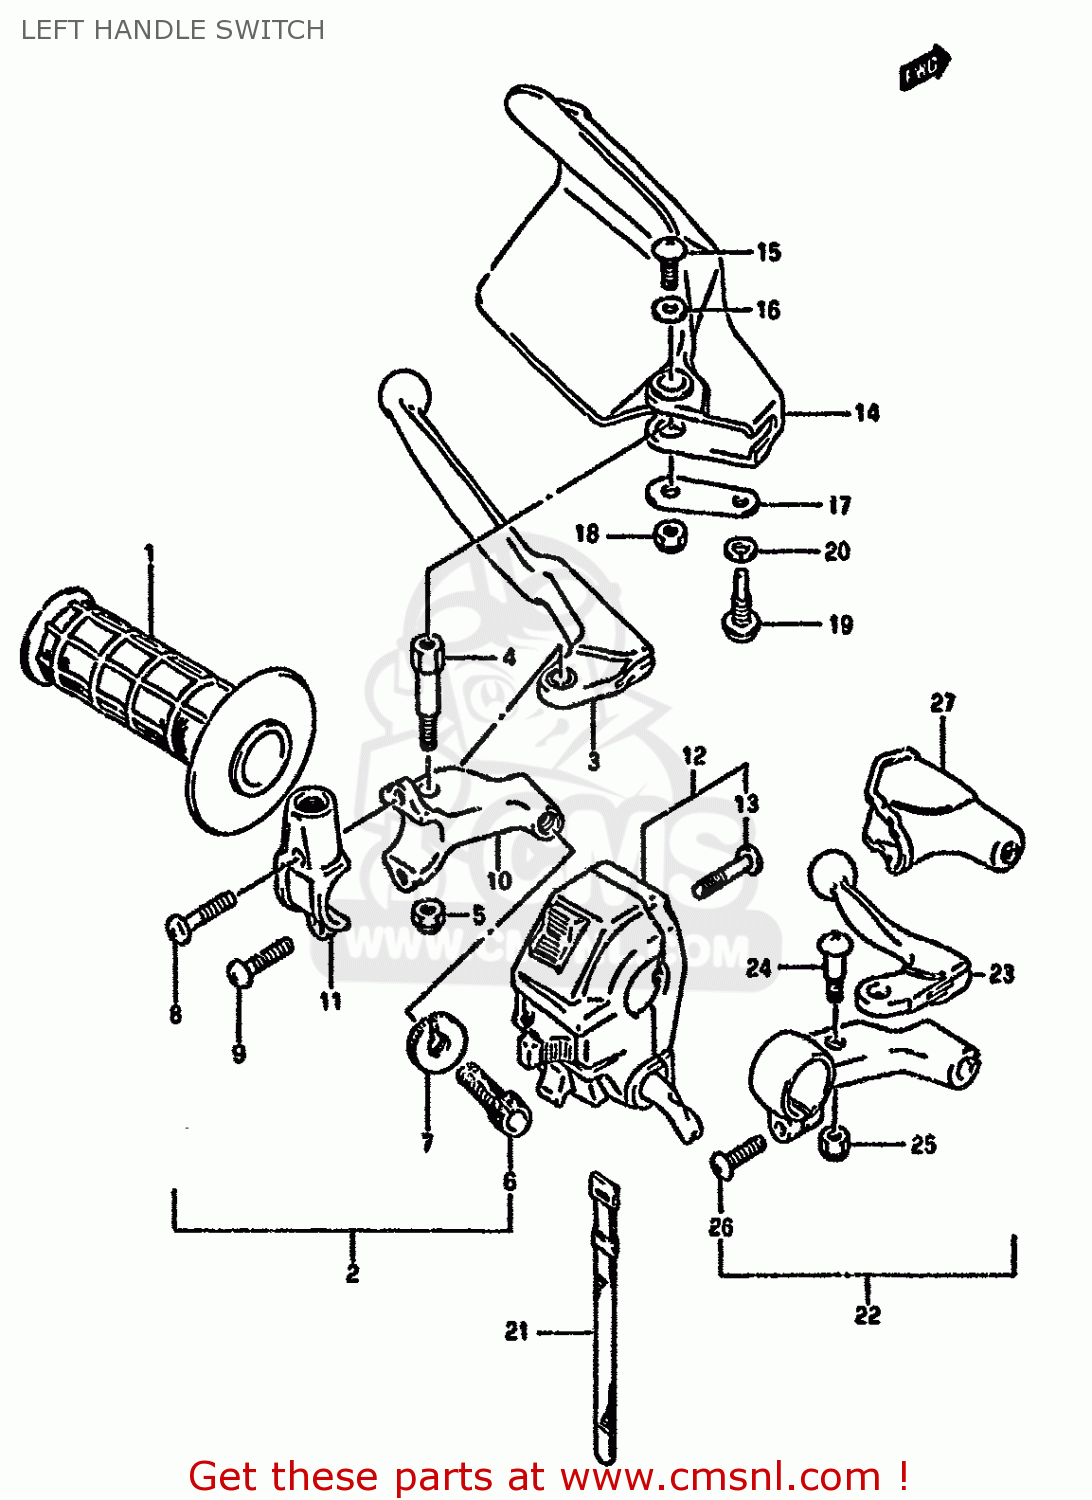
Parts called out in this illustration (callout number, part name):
1	GRIP,L
2	LEVER ASSY,CLUTCH
3	LEVER,CLUTCH
4	BOLT,LEVER SET
5	NUT 6MM
6	ADJUSTER,CABLE
7	NUT,LOCK
8	SCREW
9	SCREW(5X14)
10	HOLDER,CLUTCH LEVER
11	BRACKET,HOLDER
12	SWITCH ASSEMBLY,HANDLE,LEFT
13	SCREW
14	COVER,KNUCKLE,L
15	SCREW(5X10)
16	WASHER(5.5X16X1.5)
17	PLATE,KNUCKLE COVER,L LWR
18	NUT
19	SCREW
20	WASHER,LOCK
21	CLAMP(L:120)
22	LEVER ASSEMBLY,DECOMPRESSION
23	LEVER,DECOMP
24	BOLT,LEVER PIVOT
25	NUT
26	SCREW
27	COVER,DECOMP LEVER DUST
